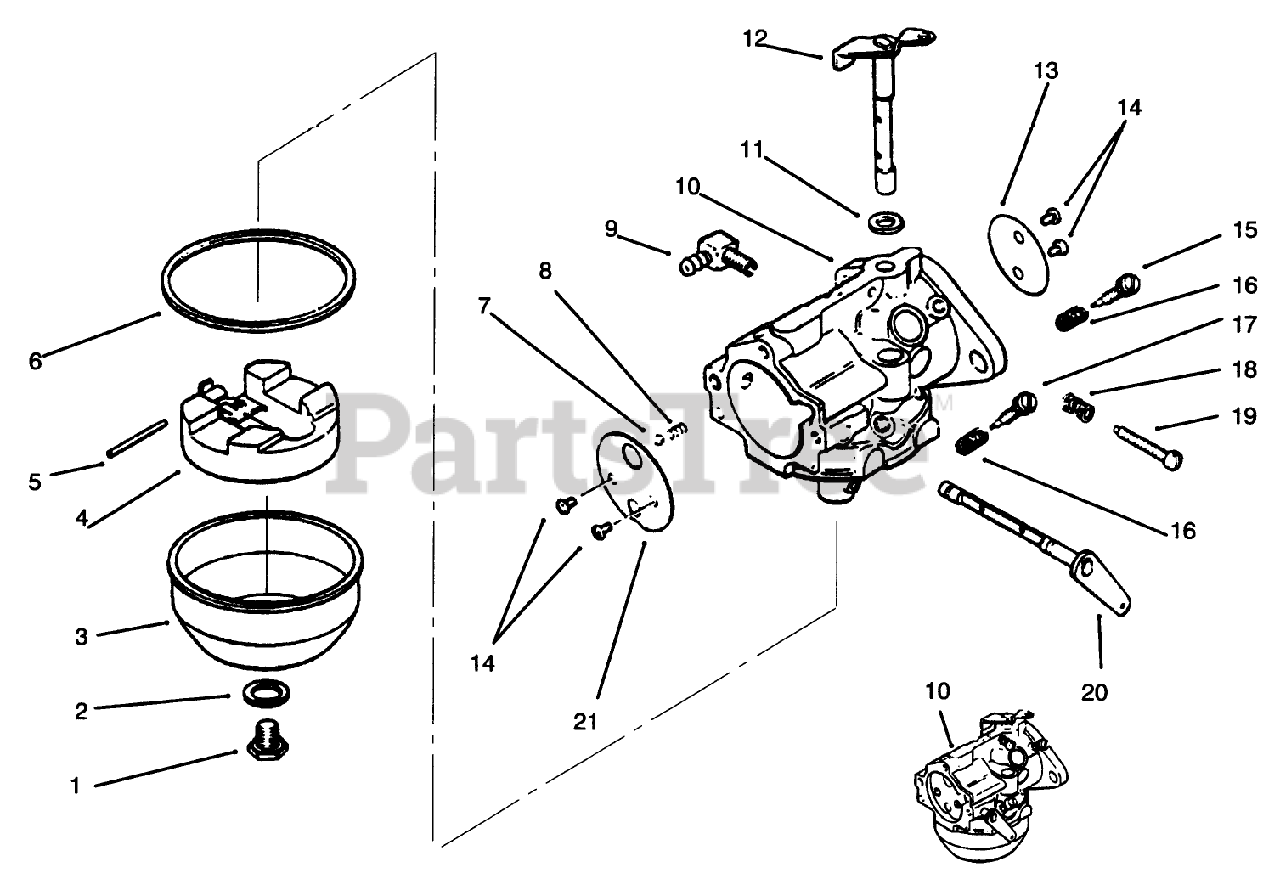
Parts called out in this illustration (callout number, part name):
1	KOHLER 25-100-05
2	KOHLER 25-041-03
3	KOHLER 25-104-01
4	KOHLER 25-757-09
5	Pin-Float
6	KOHLER 25-041-04
7	KOHLER 25-194-01
8	KOHLER 25-089-03
10	KOHLER 47-853-29
11	Seal ASM
12	VNDR #14-144-25
13	VNDR #47-146-10
14	KOHLER 25-086-27
15	KOHLER 25-368-01
16	KOHLER 25-089-02
17	KOHLER 25-368-03
18	KOHLER 25-089-04
19	KOHLER 25-086-26
20	KOHLER 47-090-38
21	VNDR #47-146-09
